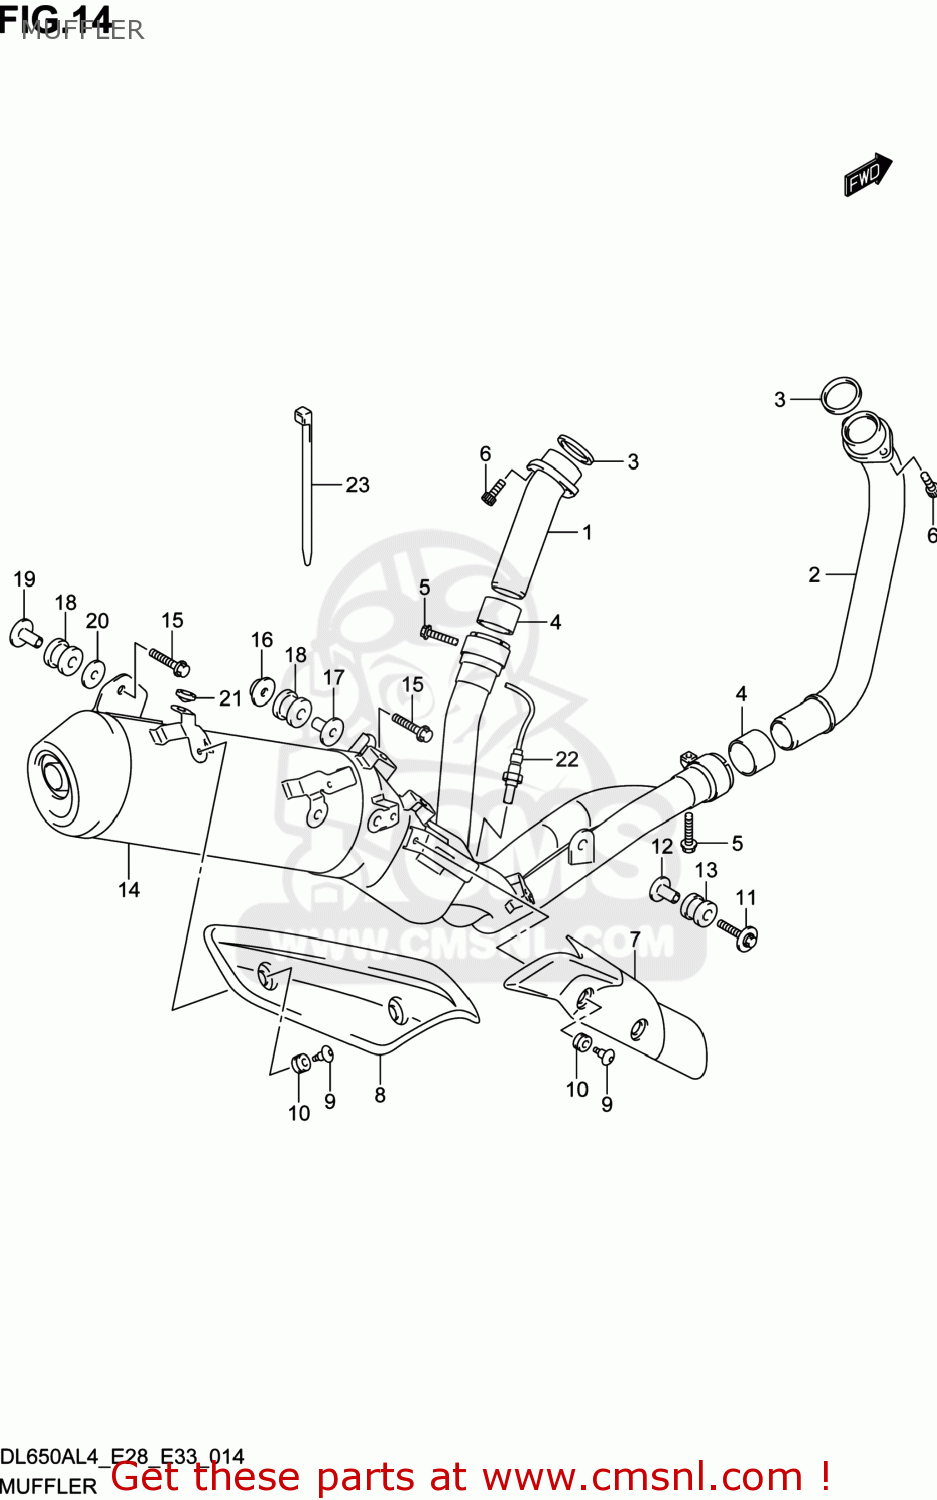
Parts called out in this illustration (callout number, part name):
1	PIPE,EXHAUST RR
2	PIPE,EXHAUST FR
3	GASKET,EXHAUST PIPE (NAS)
4	CONNECTOR,EXHAUST
5	BOLT(8X35)
6	BOLT(8X25)
7	COVER,MUFFLER FR
8	COVER,MUFFLER
9	SCREW(6X20)
10	CUSHION
11	BOLT(8X45)
12	SPACER(8.6X12X24.2)
13	CUSHION
14	MUFFLER
15	BOLT(8X45)
16	NUT,MUFFLER SUPPORT FR
17	SPACER(8.6X12X27.1)
18	CUSHION
19	NUT,MUFFLER SUPPORT
20	WASHER(8.5X33X1.5)
21	CUSHION
22	SENSOR,OXYGEN
23	CLAMP(L:145)
